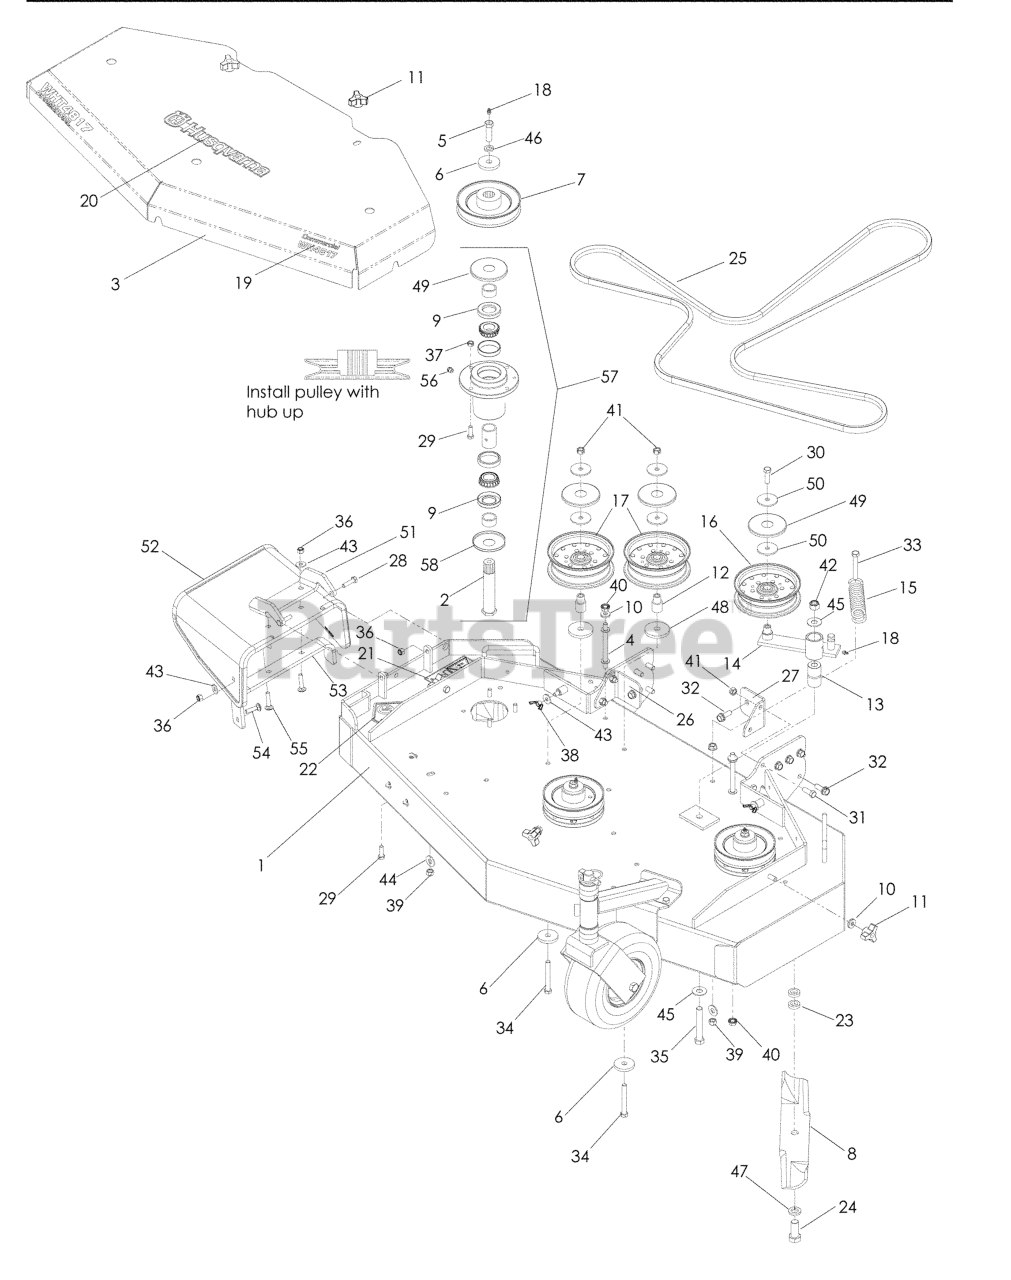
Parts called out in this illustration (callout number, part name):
1	DECK W/DECALS 48"
2	SPINDLE 52/61
3	BELT SHIELD, 48" ORANGE
4	SHIELD SPACER
5	HCS 7/16-20 GD 8 SPEC
6	SPINDLE WASHER
7	PULLEY, 52
8	BLADE OEM 16 1/4"
9	SHAFT SEAL
10	WASHER, 3/8 SEALING
11	KNOB, THREE PRONG
12	IDLER BUSHING
13	PIVOT BUSHING
16	IDLER PULLEY
17	IDLER PULLEY (TALL)
18	ZERK
19	DECAL WH4817
20	DECAL, HUSQ 15" BLUE
21	DECAL, EURO SEVERING
22	DECAL, CPSC
23	BLADE SPACERS
24	HCS 5/8-18X1-1/2 GR5 TPBLT ZD
26	DECK SLIDE, RT
27	DECK SLIDE, LT
28	HCS 5/16C X 1 1/4
29	HCS 5/16C X 1
30	HCS 3/8C X 1 1/4 GR5
31	HCS 3/8-16X1.GRD.5.ZD
32	4CS 3/8C X 1 SERRATED HEAD
33	HCS 3/8C X 2 1/2
34	HCS 3/8C X 3
35	HCS 1/2C X 3 1/4
36	NUT 5/16 NYLOC
37	NUT 5/16C CENTERLOCK
38	WINGNUT, 5/16C NYLOC
39	NUT 3/8-16 NYLOC
40	NUT 3/8C WHIZ
41	NUT 3/8C CENTERBLOCK
42	NUT 1/2-13 HEX NYLOC ZD
43	WASHER 5/16 FLAT
44	WASHER 3/8 FLAT
45	WASHER 1/2 FLAT
46	WASHER 7/16 LOCK
47	LOCKWASHER 5/8
48	WASHER, 3/8 SPEC
49	TOP DUST CAP
50	HEAVY WASHER
51	PIVOT BRACKET - CHUTE
52	CHUTE, RUBBER DISCHARGE WB
53	BRKT, REINF-CHUTE WB
54	BOLT, CARRIAGE 5/16X1-1/4
55	RHSNB 5/16-18 X 1-1/2 GR 5 ZD
56	PLUG-VENTED
57	SPINDLE ASM KIT, WHT/KIKW
58	BOTTOM DUST CAP
